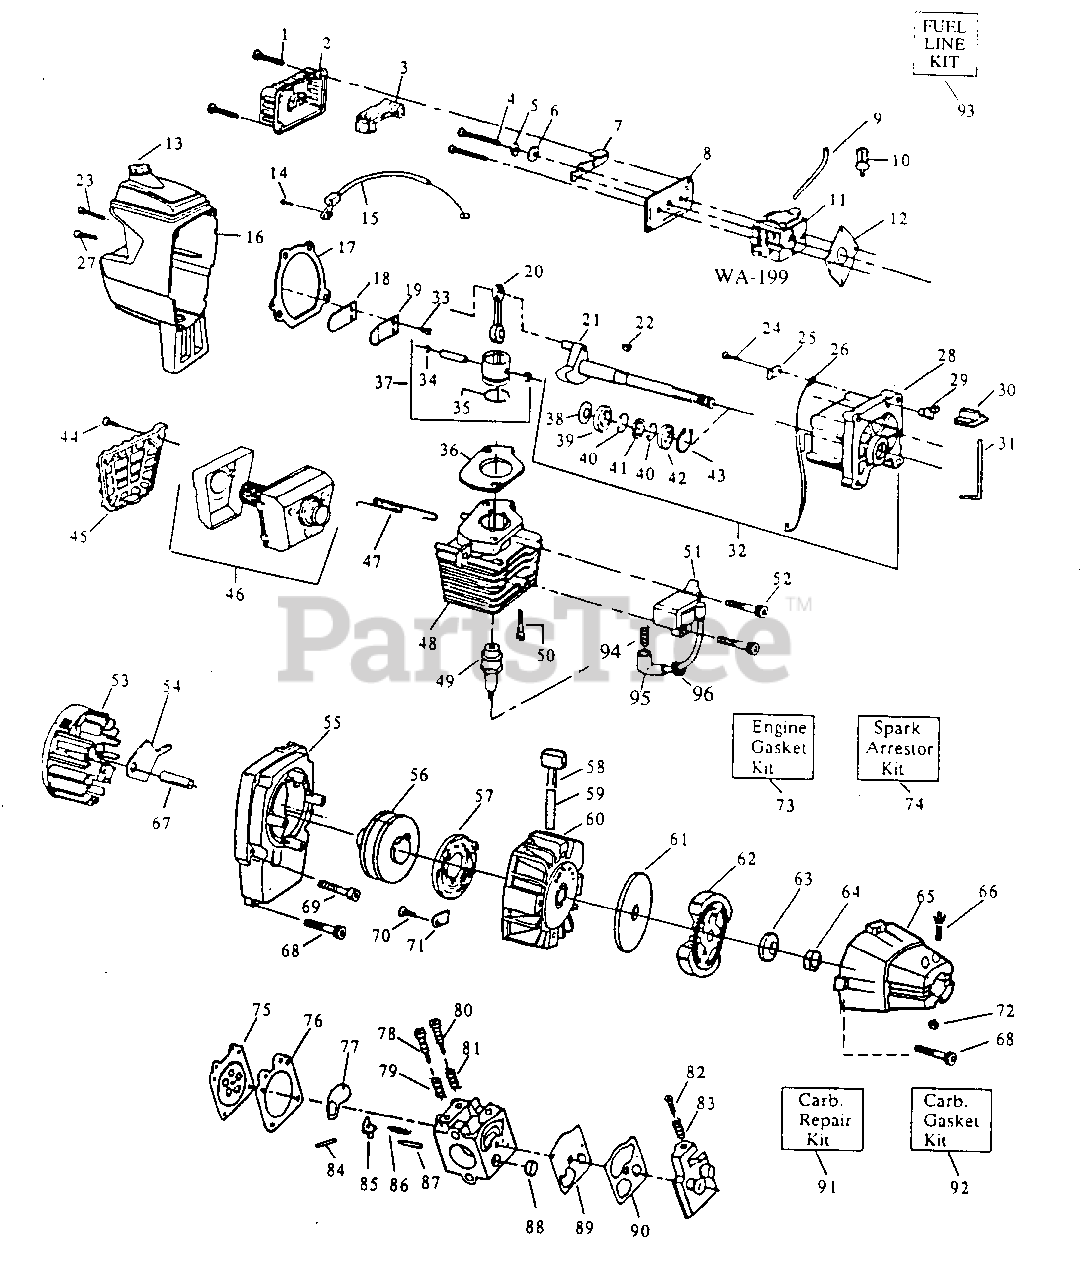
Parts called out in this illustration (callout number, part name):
2	Air Filter Cover
3	Air Filter
4	Screw
5	Spacer
6	Wave Washer
7	Choke Shutter
8	Air Filter Plate
9	Fuel Line
10	Fuel Pick-up Assy.
11	Carburetor (WA-199)
12	Carburetor Gasket
13	Fuel Cap Assy.
15	Throttle Cable Assy.
16	Shroud & Tank Assy.
19	Reed Stop
20	Connecting Rod Assy.
21	Crankshaft Assy.
22	Flywheel Key
25	Kill Switch Insulator
26	Lead Wire
28	Crankcase Assy.
29	Kill Switch Ramp
30	Kill Switch Button
31	Kill Switch Spring
32	Crankcase & Crankshaft Assy.
34	Piston Pin Retainer
35	Piston Ring
36	Cylinder Gasket
37	Piston Kit
39	Inner Bearing
40	Retaining Ring
41	Crankshaft Seal
42	Outer Bearing
43	Crankshaft Retaining Ring
45	Muffler Guard
46	Muffler Kit
47	Muffler Spring
48	Cylinder
49	Spark Plug
51	Ignition Module Kit
52	Screw
53	Flywheel Assy.
54	Flywheel Counterweight
55	Fan Housing
56	Starter Pulley
57	Starter Spring
58	Starter Handle
59	Rope Kit
60	Pulley Housing Assy.
61	Clutch Washer
62	Clutch Assy. Kit
65	Clutch Housing
71	Pulley Retainer
73	Engine Gasket Kit
74	Spark Arrestor Kit
75	Metering Diaphragm
76	Metering Diaphragm Gasket
77	Circuit Plate Gasket
78	Hi Speed Needle
79	Hi Speed Needle Spring
80	Idle Needle
81	Idle Needle Spring
82	Idle Speed Screw
83	Idle Speed Spring
84	Metering Pin
85	Metering Lever
86	Metering Lever Spring
87	Indlet Needle Valve
88	Inlet Screen
89	Pump Diaphragm
90	Pump Gasket
91	Carb. Kwik Repair Kit
92	Carb. Gasket/Diaphragm
93	Fuel Line Kit
94	Connector Spark Plug
95	Boot Spark Plug
96	Grommet Plug Wire
